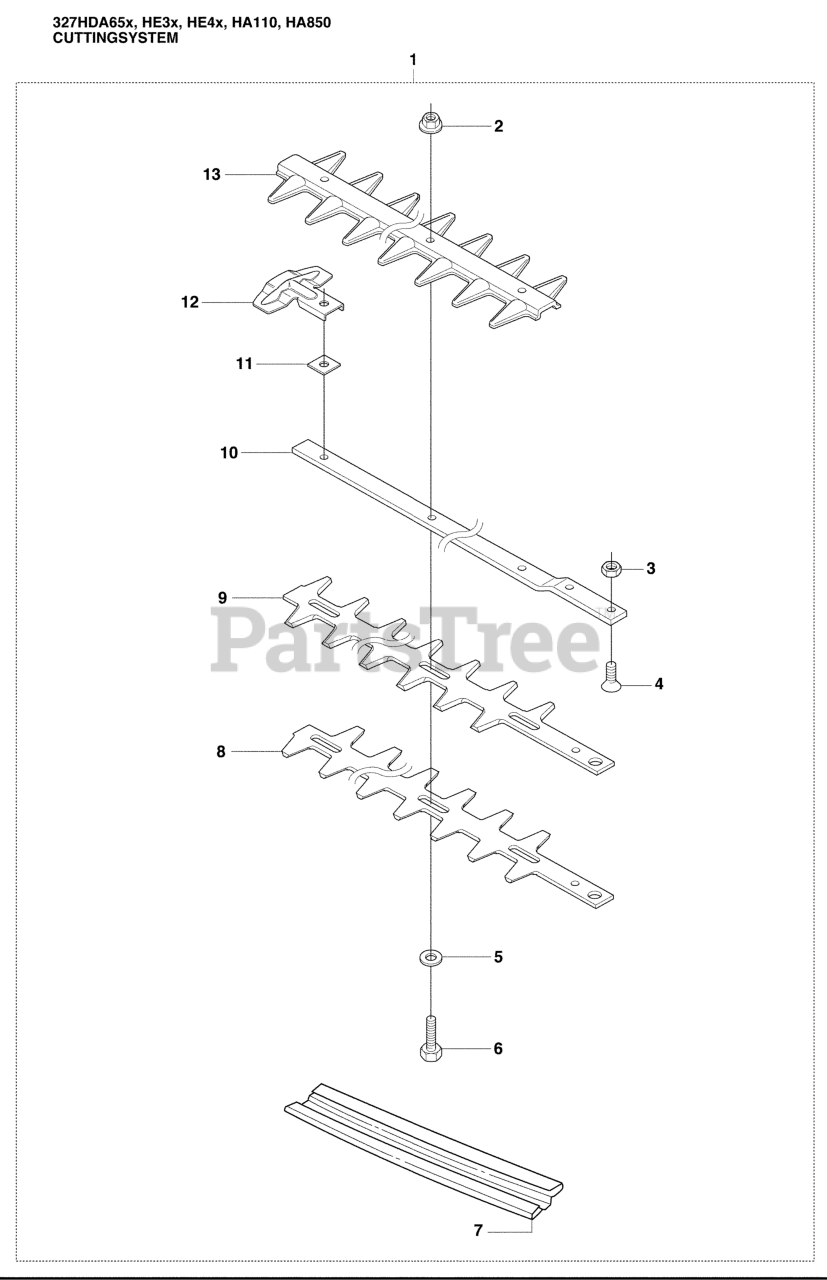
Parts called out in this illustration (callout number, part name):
11	WASHER STEEL
12	PROTECTOR
13	PLATE
